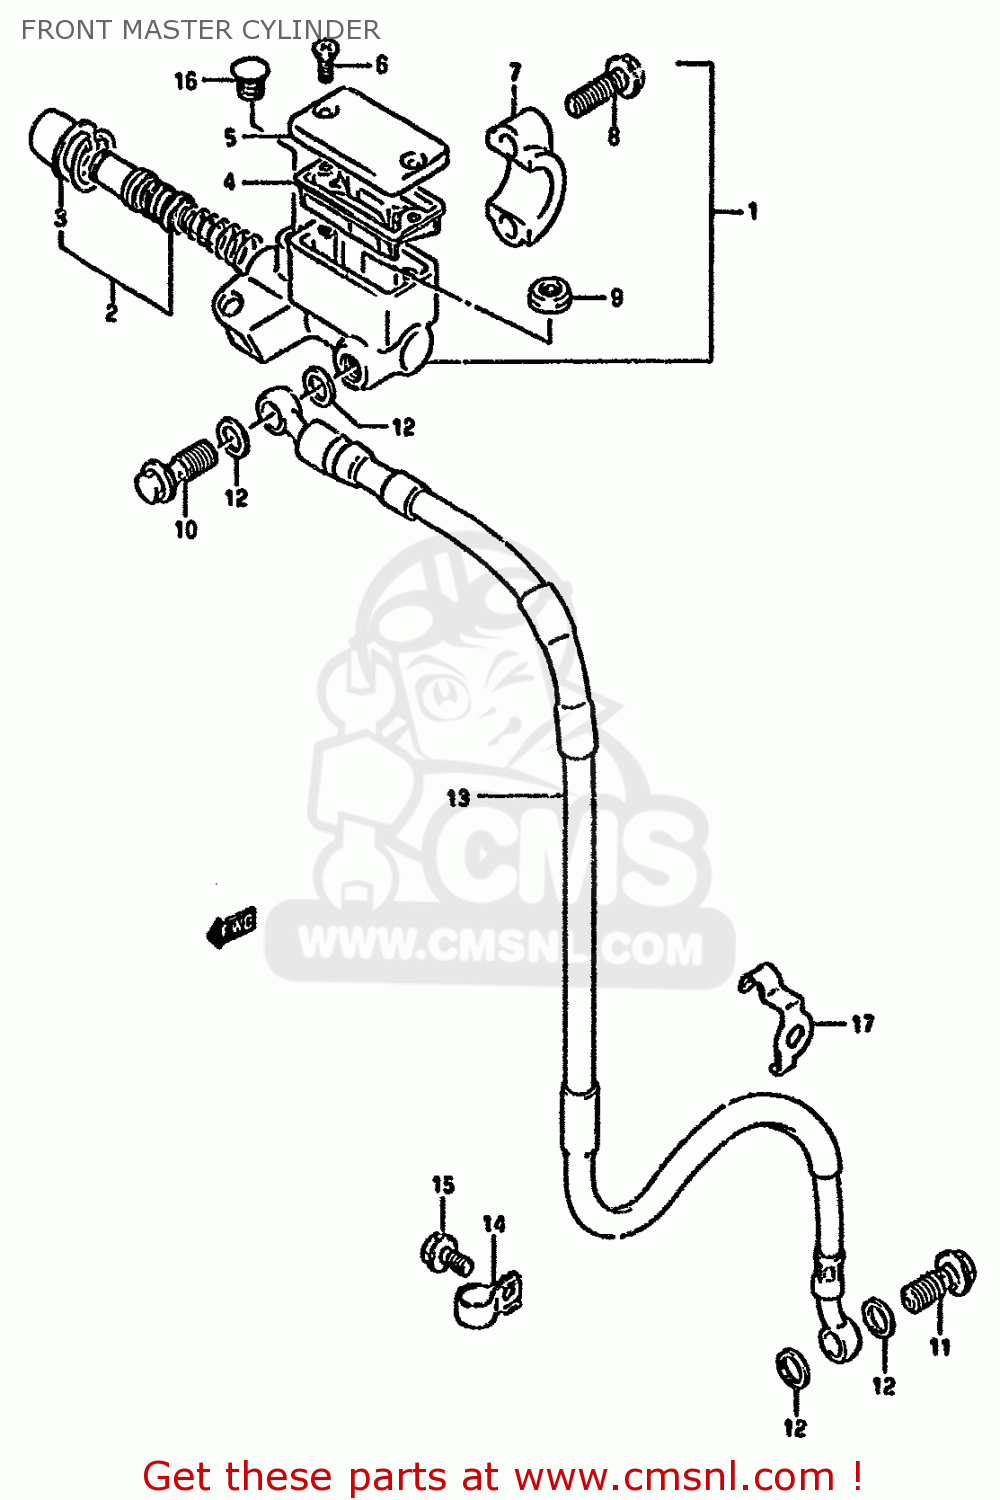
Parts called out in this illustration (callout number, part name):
1	CYLINDER ASSEMBLY,FRONT MASTER
2	PISTON & CUP SET
3	BOOT
4	DIAPHRAGM
5	CAP
6	SCREW
7	HOLDER
8	BOLT
9	SEPARATOR
10	BOLT UNION
11	BOLT UNION
12	WASHER(10X15X1.5)
13	HOSE,FR BRAKE
14	CLAMP,FR BRAKE HOSE NO.2
15	BOLT
16	CAP(OD:14)
17	CLAMP,FRONT BRAKE HOSE
